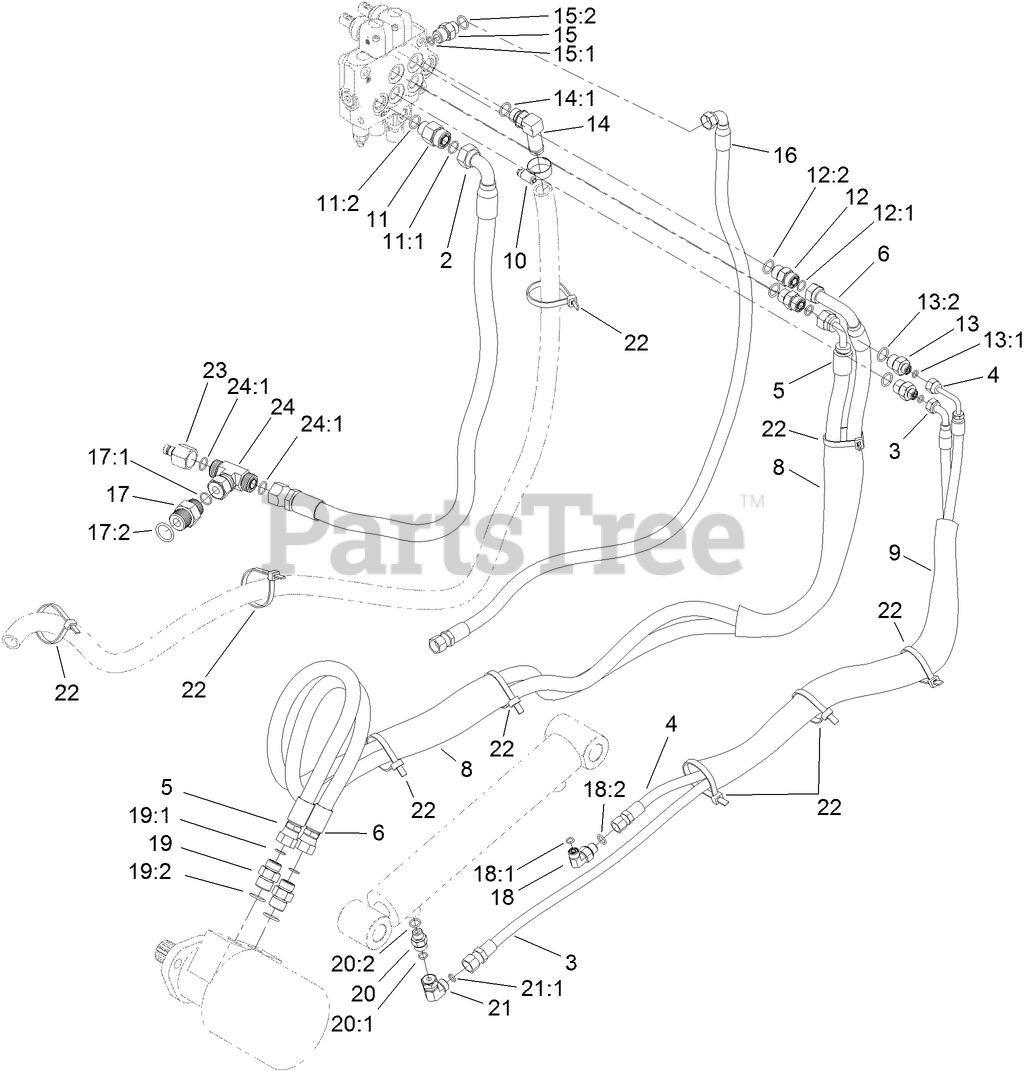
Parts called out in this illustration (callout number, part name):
2	HOSE-HYD
3	HOSE-HYD
4	HOSE-HYD
5	HOSE-HYD
6	HOSE-HYD
8	SLEEVE-PROTECTIVE
9	SLEEVE-PROTECTIVE
10	CLAMP-HOSE
11	FITTING-STR
11:1	O-RING
11:2	O-RING
12	FITTING-STRAIGHT
12:1	O-RING
12:2	O-RING
13	FITTING-STR
13:1	O-RING
13:2	O-RING
14	FITTING-ELB 90
14:1	O-RING
15	FITTING-STRAIGHT
15:1	O-RING
15:2	O-RING
16	HOSE-HYD
17	FITTING-STRAIGHT
17:1	O-RING
17:2	O-RING
18	FITTING-ELBOW 90
18:1	O-RING
18:2	O-RING
19	FITTING-STRAIGHT
19:1	O-RING
19:2	O-RING
20	VALVE-CHECK
20:1	O-RING
20:2	O-RING
21	FITTING-HYD, 90 DEG
21:1	O-RING
22	TIE-CABLE
23	NIPPLE
24	FITTING-HYD, TEE
24:1	O-RING
